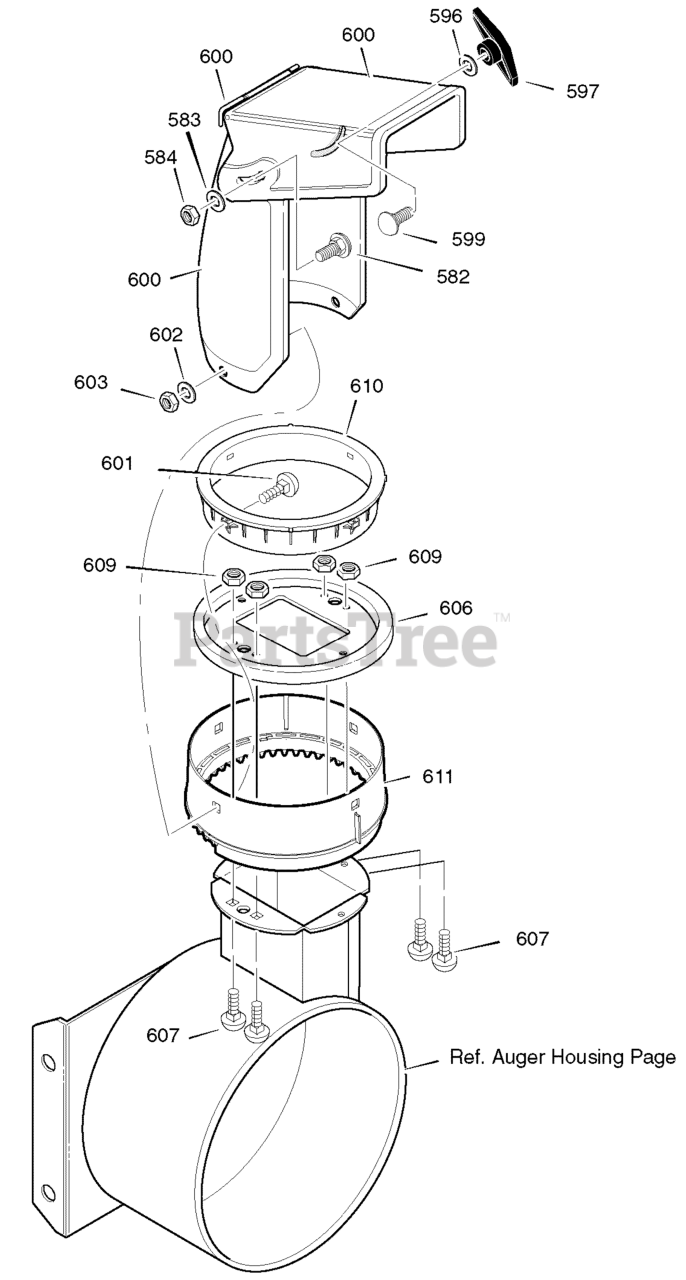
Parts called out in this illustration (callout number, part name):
582	BOLT, 5/16-18 X 1.00 CARG.
583	WASHER, FLAT
584	NUT, 5/16-18 NYLOCK
596	WASHER
597	KNOB, WING 3.00
599	BOLT, 5/16-18X1.125
600	CHUTE ASSEMBLY
601	BOLT
602	WASHER, FLAT
603	NUT, 5/16-18 HEXNYL
606	CHUTE COLLAR
607	SCREW, 1/4-20 X .75
609	NUT, 1/4-20 HEX NYLOCK
610	RETAINER RING INNER
611	RETAINER RING OUTER
